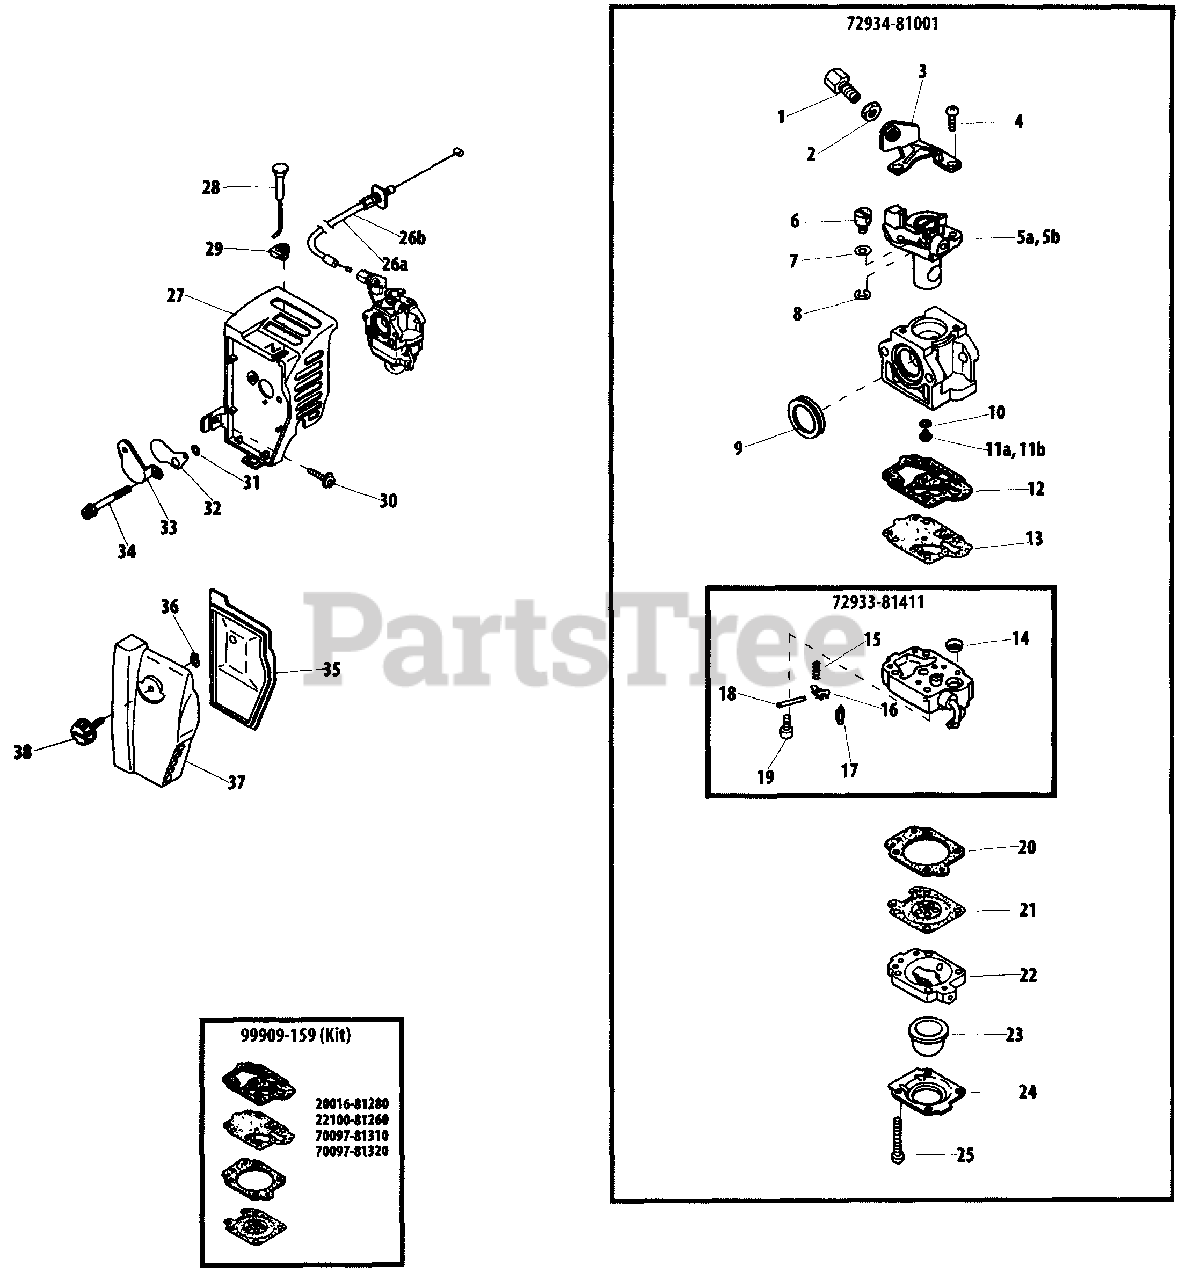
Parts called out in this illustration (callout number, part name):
1	ADJUSTER, THROTTLE CABLE
2	NUT, ADJUSTER LOCK M7
3	BRACKET, THROTTLE CABLE
4	SCREW
5A	THROTTLE VALVE ASSY
5B	THROTTLE VALVE ASSY
6	SWIVEL
7	WASHER
8	E-RING
9	RING, PACKING
10	O-RING
11A	JET
11B	MAIN JET (#37)
12	GASKET, PUMP
13	DIAPHRAGM, PUMP
14	SCREEN, FUEL INLET
15	SPRING, METERING LEVER
16	LEVER, METERING
17	VALVE, INLET NEEDLE
18	PIN, METERING LEVER
19	SCREW
20	GASKET, METERING DIAPHRAGM
21	DIAPHRAGM, METERING
22	BODY ASSY, PURGE
23	BULB, PURGE
24	RETAINER, PURGE BULB
25	SCREW
26A	CABLE, THROTTLE
26B	CABLE, THROTTLE
27	CASE, AIR FILTER
27	CASE, AIR FILTER (NON EPA)
28	ROD, CHOKE
29	GROMMET
30	SCREW M5
31	WASHER 5
32	PLATE, CHOKE
33	PLATE, PREVENT
34	BOLT M5×45
35	FILTER, AIR
36	E-RING
37	COVER, AIR FILTER
38	THUMBSCREW
